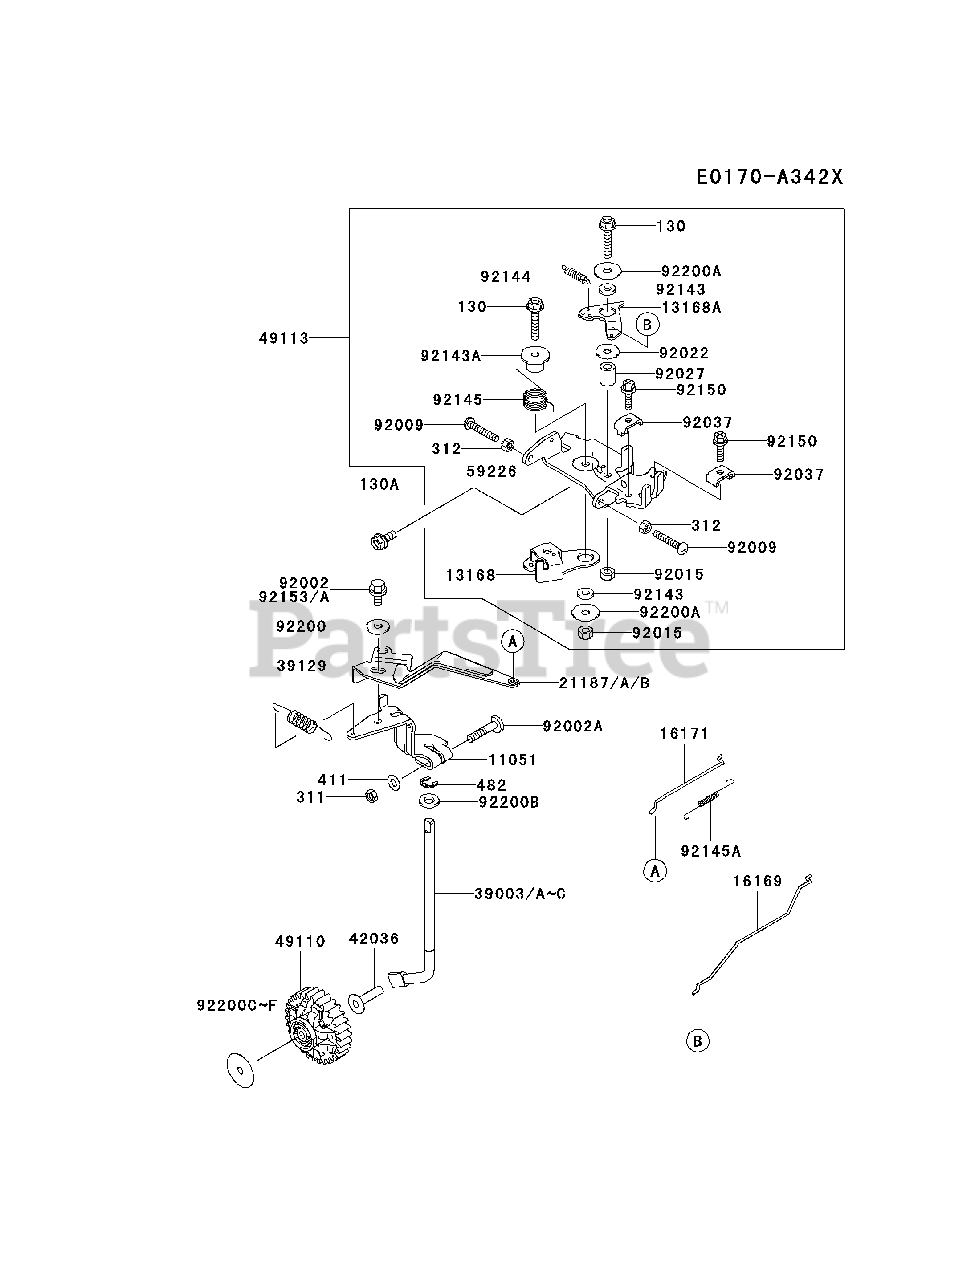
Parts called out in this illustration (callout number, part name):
130A	BOLT-FLANGED,6X14
311	NUT-HEX,6MM
312	NUT-HEX,5MM
411	WASHER-PLAIN,6MM
482	CIRCLIP-TYPE-E,7MM
